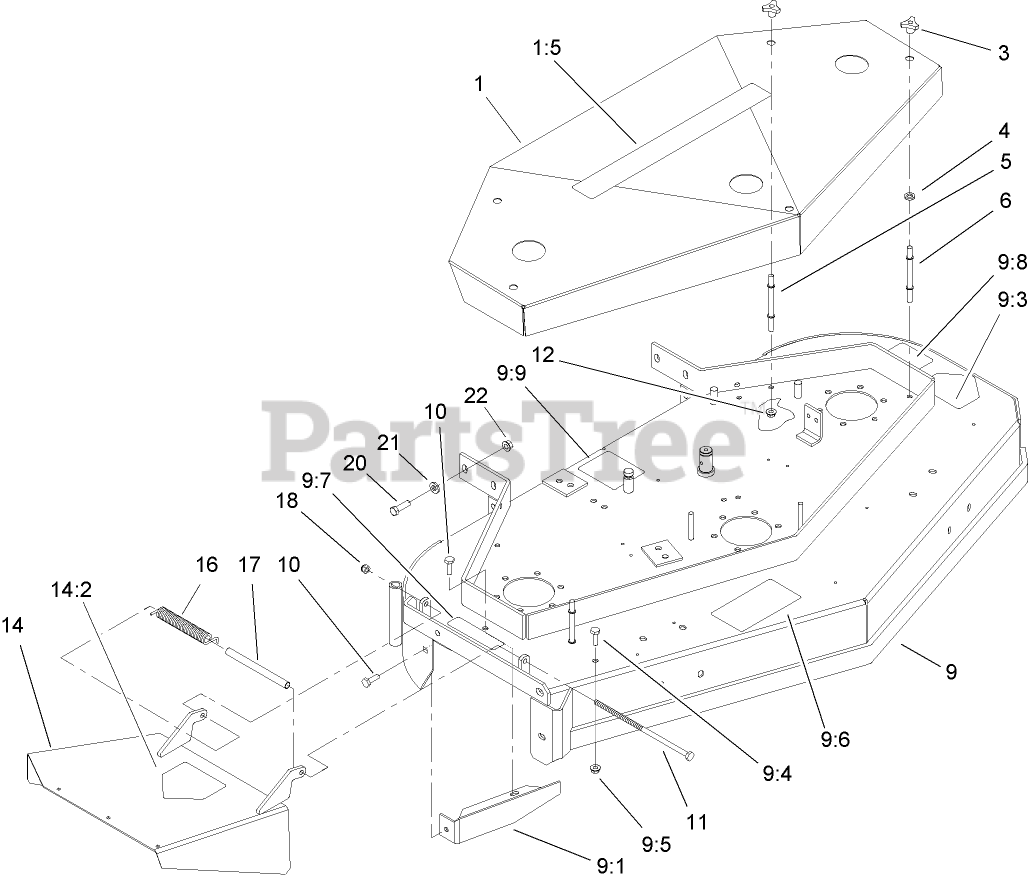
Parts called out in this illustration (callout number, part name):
1	SHIELD-BELT
3	KNOB-HANDLE
4	WASHER
5	STUD-SHIELD, BELT (LONG)
6	STUD-SHIELD, BELT (SHORT)
9:1	BAFFLE-DOGLEG
9:3	DECAL-DANGER
9:4	SCREW-HH
9:5	NUT-HF
9:6	DECAL-DANGER, THROWN OBJECT
9:7	DECAL-DANGER
9:8	DECAL-TORQUE, BOLT
9:9	DECAL-ROUTING, BELT
10	SCREW-HH
11	SCREW-HH
12	NUT-HF
14:2	DECAL-DANGER
16	SPRING-DEFLECTOR
17	SPACER-SPRING
18	NUT-LOCK, NI
20	SCREW-HH
21	WASHER-BELLEVILLE
22	NUT-HHF, WHIZ
